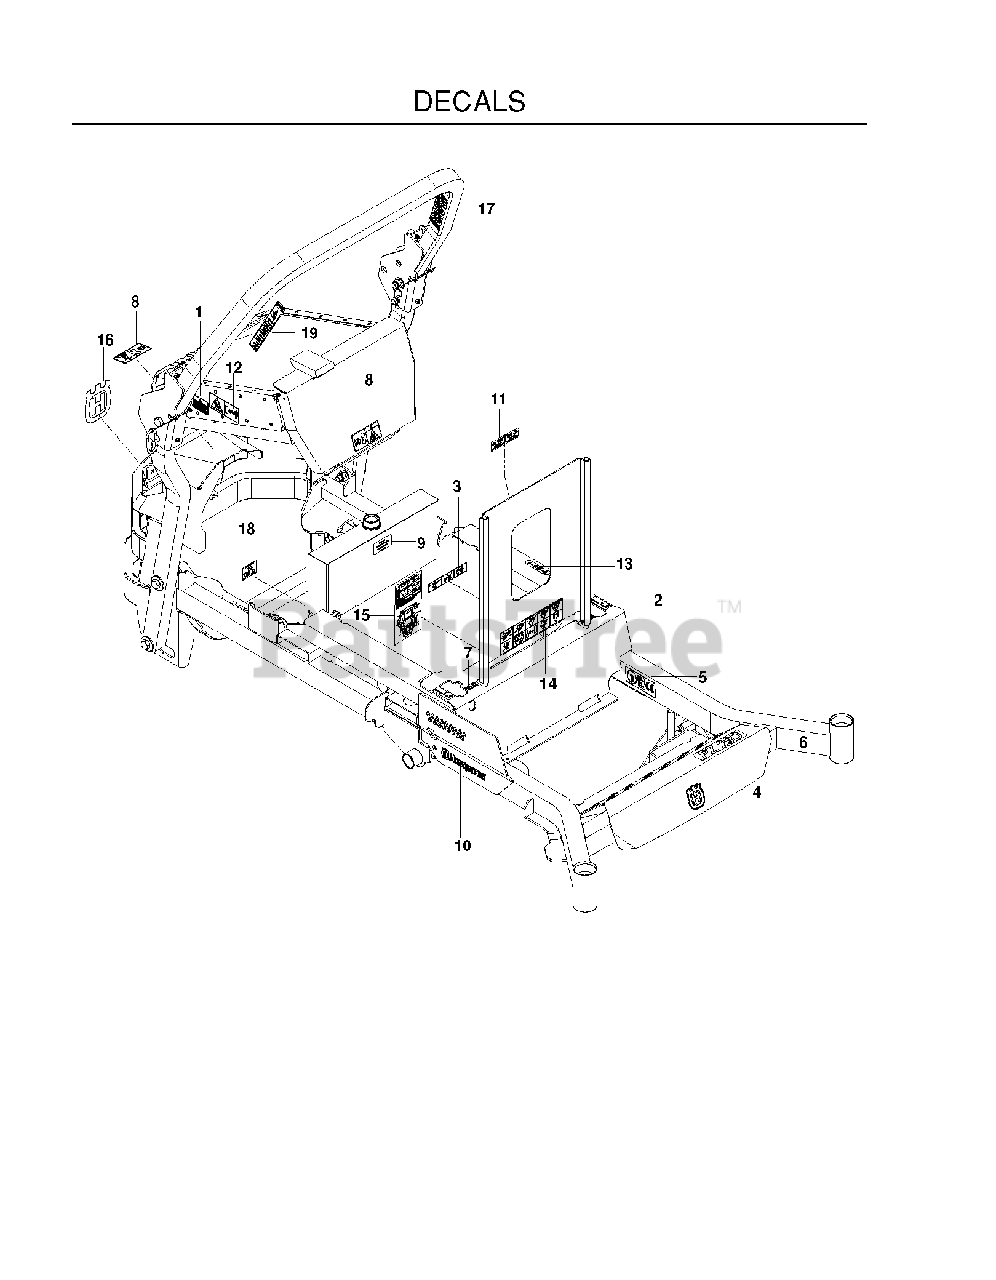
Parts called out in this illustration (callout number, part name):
1	DECAL, DEBRIS SCREEN
2	DECAL, MOTION CONTROL
3	EURO DECAL-BATTERY WARNIN6
4	DECAL.AUGER.HUSQ.CROWN.SNOW
5	CLAMP
6	DECAL, PZ29D
7	DECAL, F.S.T.
8	DECAL, BELT DRIVE
9	DECAL, OIL TANK
10	RP.DECAL.BADGE.170MM.TEXTLOGO
11	Decal, Fuse Diesel
12	Decal, Hot
13	DECAL, PARK BRAKE
14	DECAL, WARNING
15	Decal, Service, Diesel
16	DECAL, CROWN H, 110MM
17	DECAL, ROPS, DIESEL
18	DECAL, HYDRO BELT
19	DECAL, ROPS, WARNING
